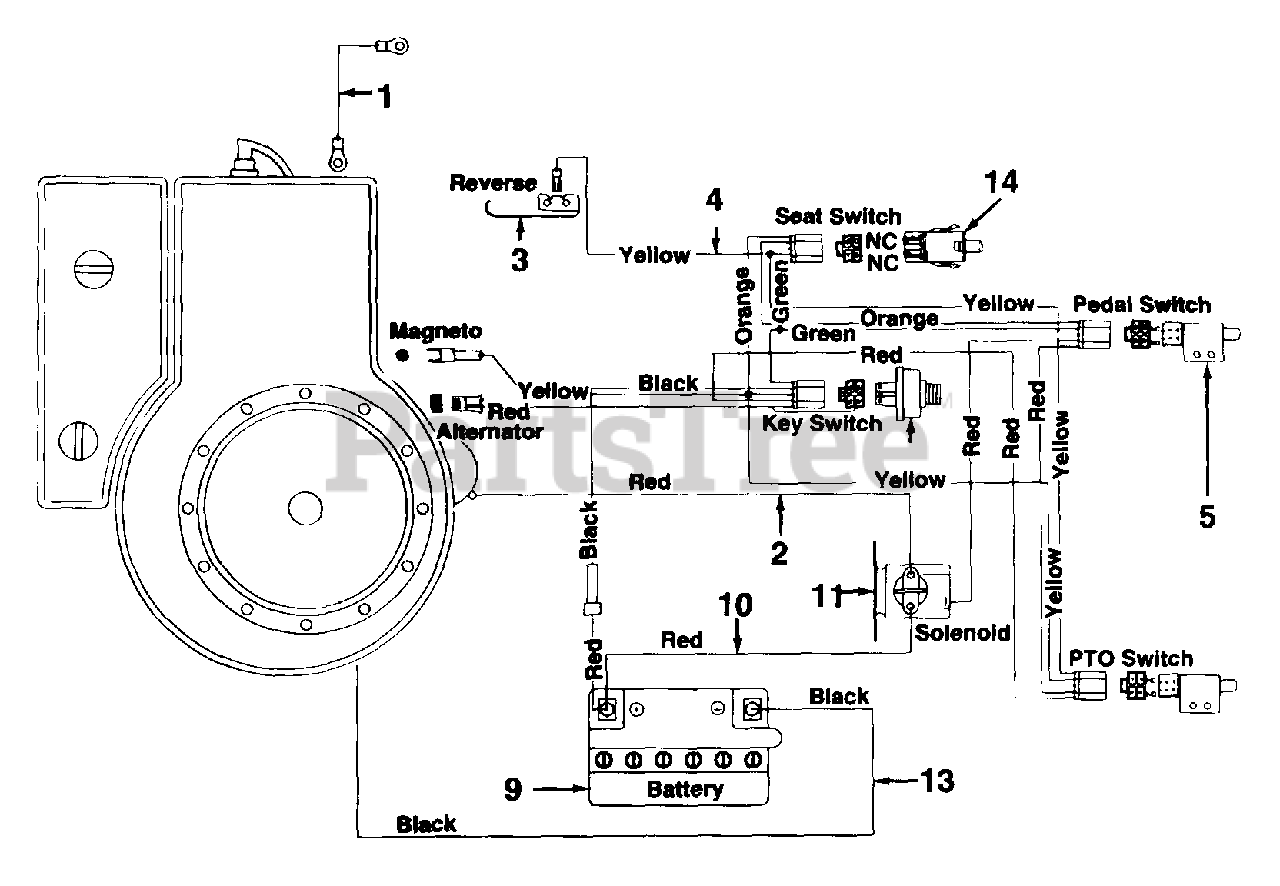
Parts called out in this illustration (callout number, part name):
1	Elec. Wire 8 Ga. x 9.0" Lg.
2	Elec. Wire 15.5" Lg. (All Except Tecumseh)
3	Spring Switch - Reverse
4	Wire Harness
5	Safety Switch
8	Ignition Switch
9	Battery 12V
10	Elec. Wire Red w/Boot
11	Solenoid
13	Elec. Wire 8 Ga. x 9.0" Lg.
14	Seat Switch
